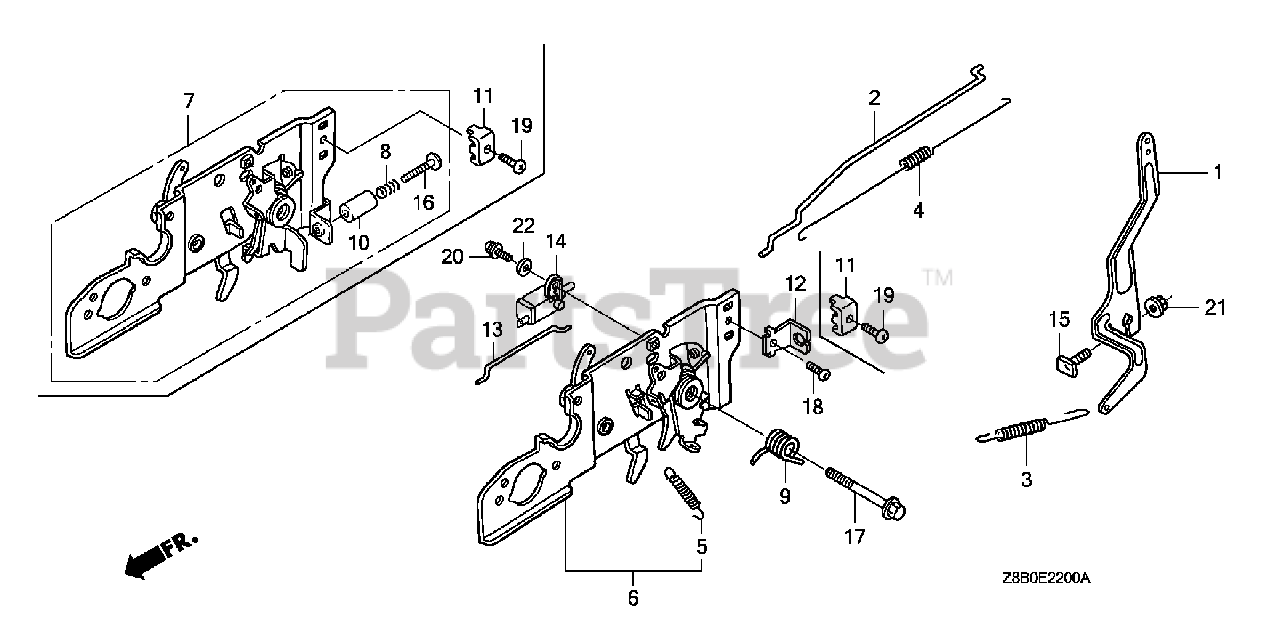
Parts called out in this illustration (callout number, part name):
1	ARM, GOVERNOR
2	ROD, GOVERNOR
3	SPRING, GOVERNOR
4	SPRING, THROTTLE RETURN
5	SPRING, LEVER
6	BASE, CONTROL
11	HOLDER, CABLE
13	ROD, CHOKE
15	BOLT, GOVERNOR ARM
17	BOLT, FLANGE (6X45) (CT200)
19	SCREW, PAN (5X16)
21	NUT, FLANGE (6MM)
